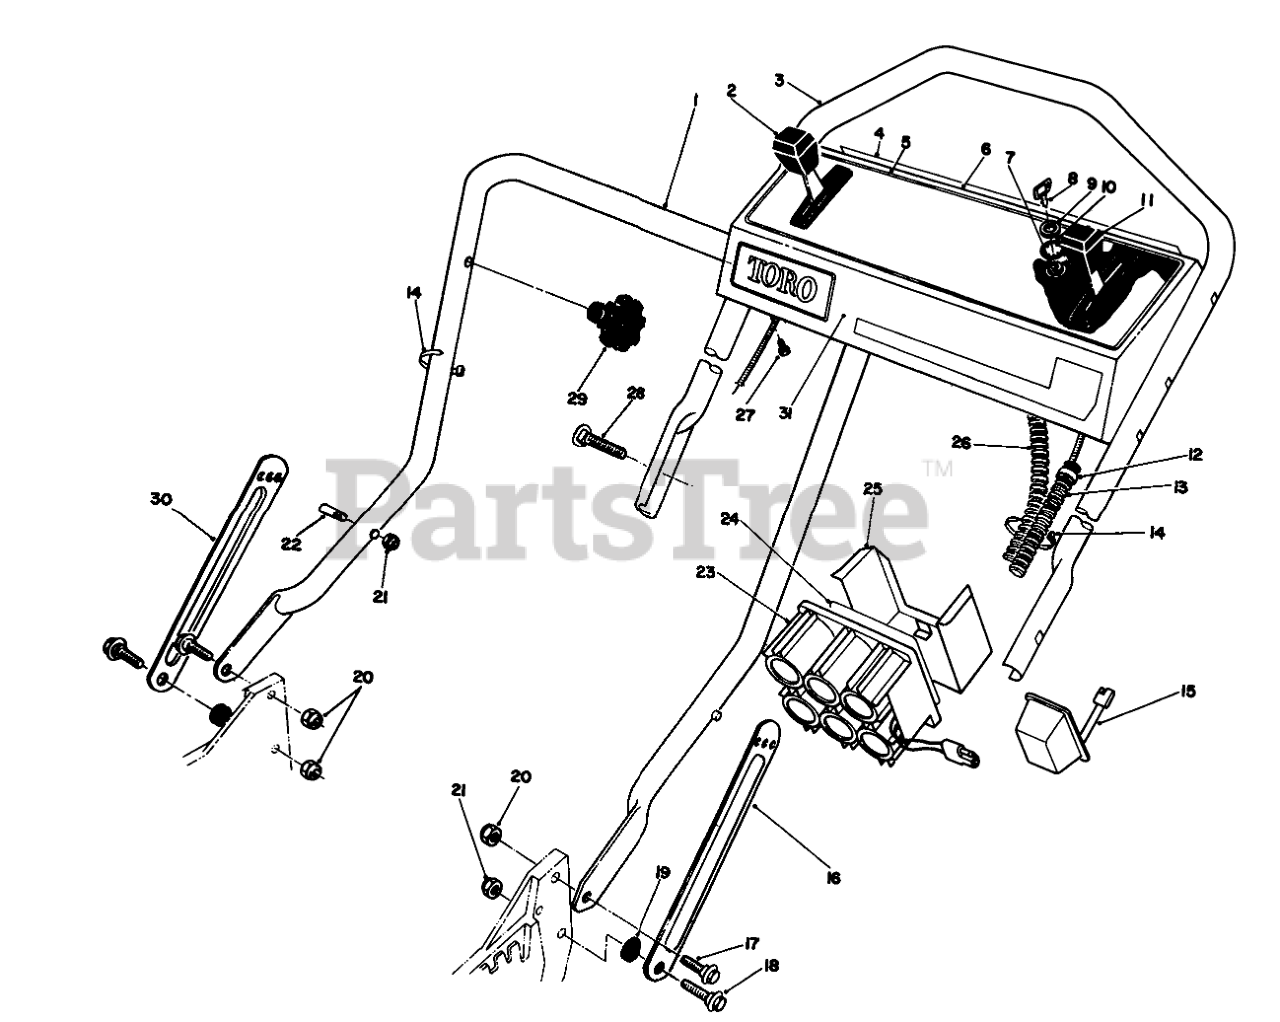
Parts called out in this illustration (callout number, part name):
1	LOWER HANDLE ASM
2	Control-Ground Speed
3	UPPER HANDLE
4	DECAL - PANEL, REAR
5	DECAL - INSTRUCTION
6	Panel-Control(Incl. Ref. #4 & 5)
7	STARTER SWITCH ASM
8	KEY-IGNITION
9	NUT-HH
10	WASHER-TOOTH, INTERNAL
11	THROTTLE CONTROL
12	FITTING-RING
13	CONTROL CABLE COVER
14	TIE-CABLE
15	Charger
16	LH HANDLE LATCH
17	SCREW-SHOULDER
18	SCREW-SHOULDER
19	SPACER
20	NUT-LOCK, NI
21	NUT-LOCK, NI
22	HANDLE PIN
23	BATTERY ASSEMBLY
24	Decal
25	Retainer-Battery
26	Harness-Wire
27	SCREW-HWHTF
28	5/16-18 X 2 HNDLE SCREW
30	RH HANDLE LATCH
31	DECAL - TORO
